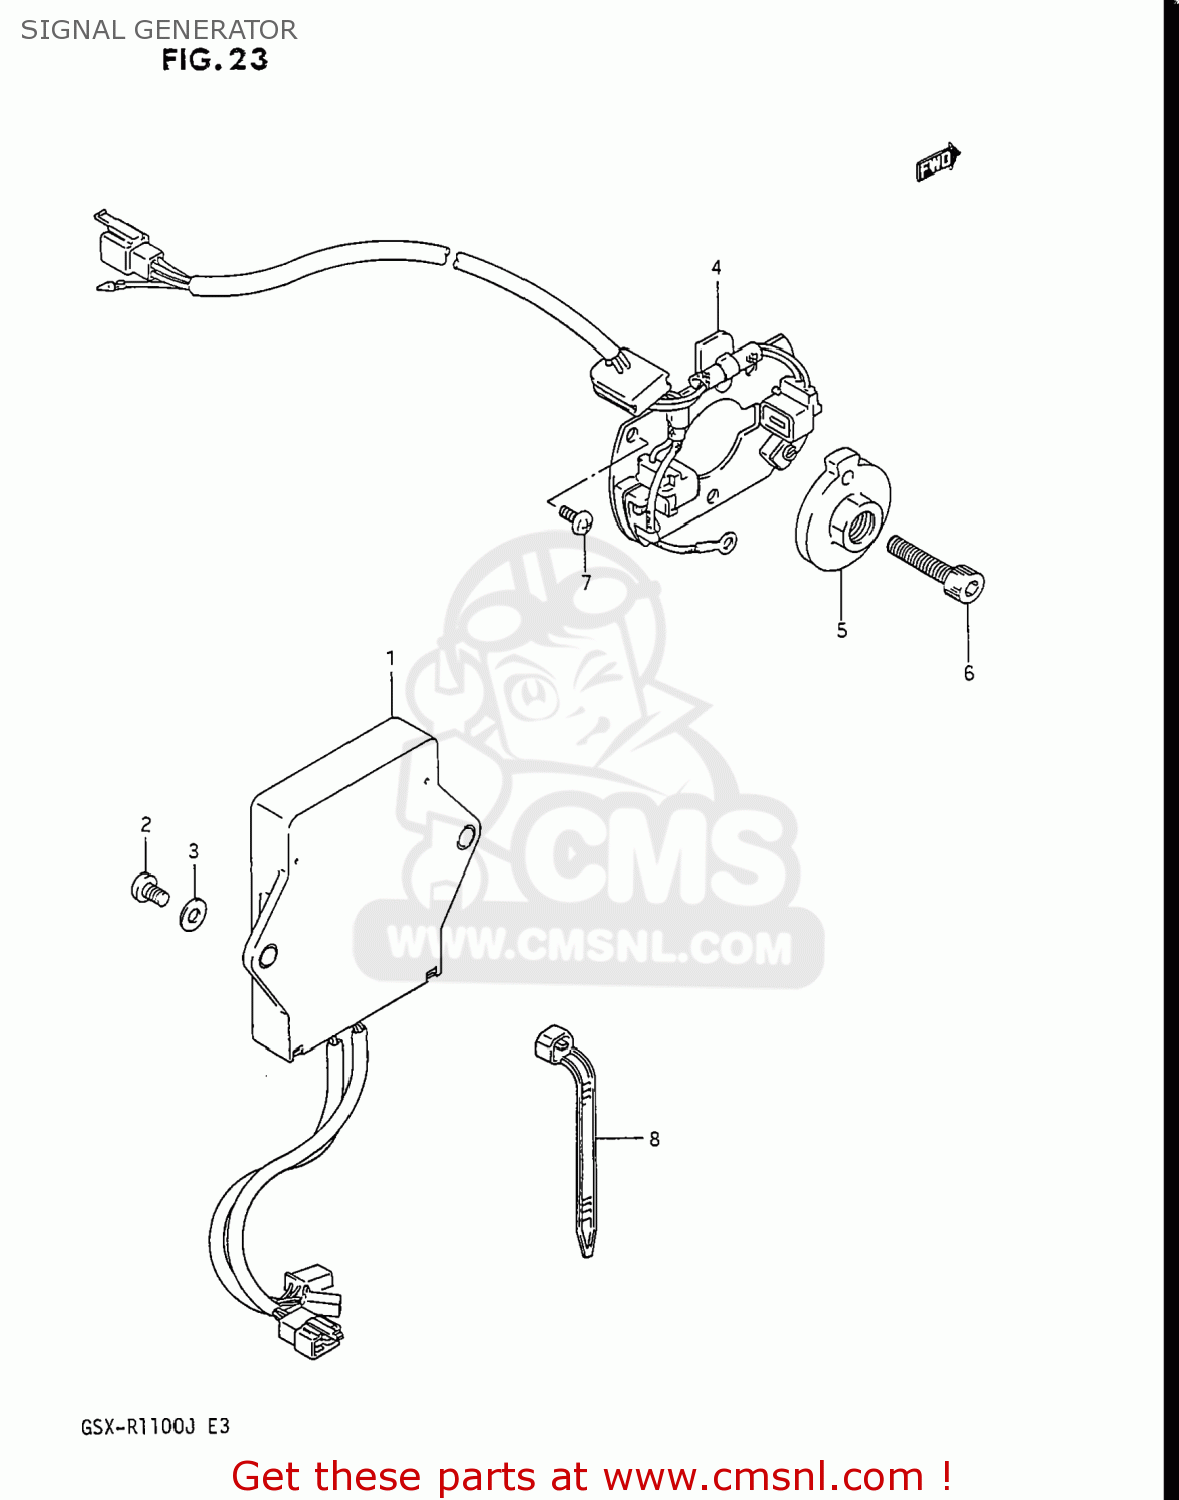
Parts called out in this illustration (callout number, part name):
1	IGNITER UNIT
2	SCREW
3	WASHER, LOWER
4	GENERATOR ASSEMBLY,SIGNAL
5	ROTOR COMP,SIGNAL
6	BOLT
7	SCREW
8	CLAMP(L:125)
